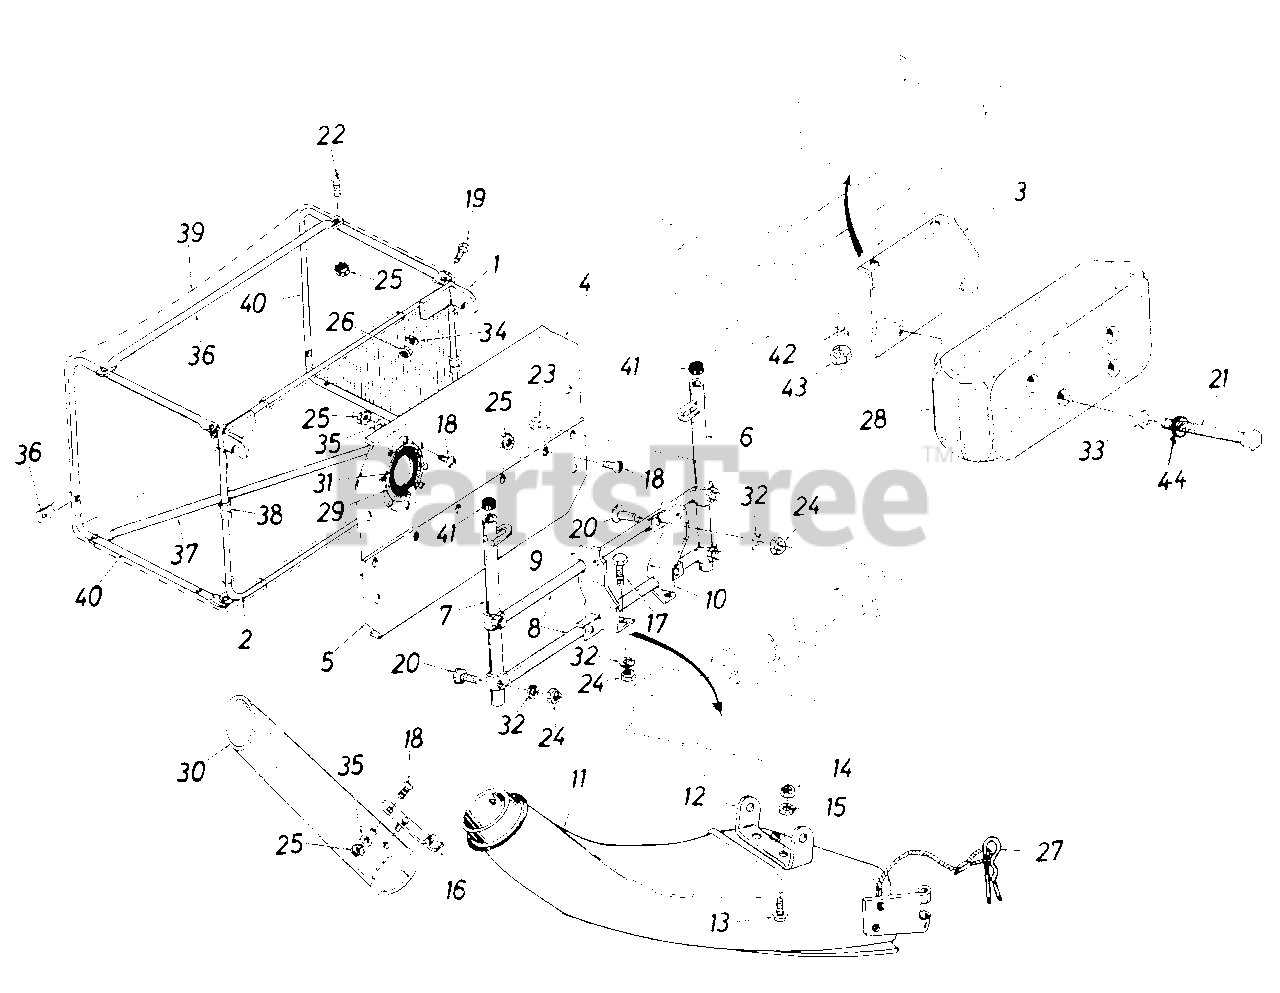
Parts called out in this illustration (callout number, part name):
1	Catcher Frame Ass'y.-Upper
2	Catcher Frame Ass'y.-Lower
3	Counterweight Support Bracket Ass'y.
4	Front Cover-Upper Half
5	Front Cover-Lower Half
6	L.H. Vertical Support Ass'y.
7	R.H. Vertical Support Ass'y.
8	Horizontal Support Tubing
9	Catcher Support Brk't. Ass'y.-R.H.
10	Catcher Support Brk't. Ass'y.-L.H.
11	Discharge Chute Ass'y.
12	Brk't. Chute Hinge
13	Carr. Bolt 1/4-20 x .62" Lg.
14	Hex Nut 1/4-20 Thd.*
15	L-Wash. 1/4" I.D.*
16	Spring Lock Ass'y.
17	Hex Bolt 5/16-18 x .75" Lg.*
18	Truss Mach. Scr. #10-24 x .38" Lg.*
19	Hex Bolt 1/4-20 x .62" Lg.*
20	Curved Carr. Bolt 5/16-18 x 1.75" Lg.
21	Hex Bolt 3/8-16 x 4.50" Lg.*
22	Truss Mach. Scr. #10-24 x 1.0" Lg.*
23	Hex Wash. Hd. AB-Tap Scr. 1/4" x .62" Lg.
24	Hex Nut 5/16-18 Thd.*
25	Hex Sems Nut #10-24 Thd.
26	Hex Nut 1/4-20 Thd.*
27	Internal Cotter Pin
28	Counter Weight-38#
29	Trim Strip-24"
30	Grass Chute Tube
31	Rubber Flap
32	L-Wash. 5/16" I.D.*
33	Fl-Wash. .406" I.D. x 1.25" O.D. x .17
34	L-Wash. 1/4" I.D.*
35	Fl-Wash. .203" I.D. x .41" O.D. x .040
36	Grass Catcher Handle
37	Grass Catcher Handle
38	Tubing Connector 1/2" I.D.
39	Grass Bag
40	Catcher Side Frame
42	L-Wash. 5/16" I.D.*
43	Hex Nut 5/16-18 Thd.*
44	Bell-Wash. 3/8" I.D. x 7/8" O.D.
